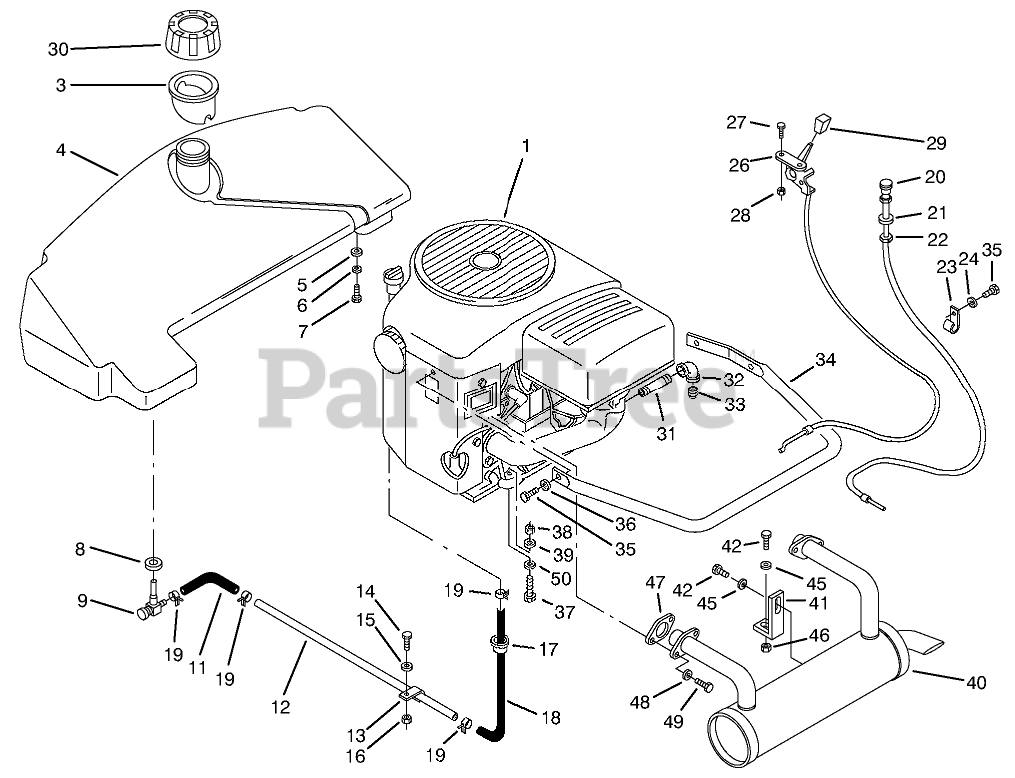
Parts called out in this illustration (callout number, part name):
1	Engine-16HP Model P216V-1/11103-D
3	FUNNEL-FUEL TANK
4	TANK-FUEL ASS'Y
5	WASHER-FLAT
6	WASHER-LOCK
7	SCREW-HH
8	BUSHING
9	VALVE-FUEL
11	HOSE-FUEL
12	TUBE FUEL LINE
13	J-CLIP
14	Bolt
15	WASHER-PLAIN
16	NUT-LOCK, NI
17	BUSHING-NYLON 1.093
18	Hose-18" Fuel
19	CLAMP-FUEL LINE
20	CONTROL-CHOKE
21	WASHER-FLAT
22	NUT-HEX PALNUT
23	CLIP
24	WASHER-FLAT
26	CONTROL-THROTTLE
27	SCREW-PPH
28	NUT-LOCK, NI
29	KNOB-CONTROL
30	GAS CAP ASM
31	NIPPLE-3/8 X 2.5
32	ELBOW 3/8 90 DEG
33	Plug
34	GUARD-AIR CLEANER
35	SCREW-HH
36	WASHER-LOCK
37	Bolt
38	NUT-LOCK, NI
39	WASHER-PLAIN
40	EXHAUST-MUFFLER
41	BRACKET-MUFFLER
42	SCREW-HH
43	WASHER-PLAIN
45	WASHER-PLAIN
46	NUT-LOCK, NI
47	GASKET
48	WASHER-LOCK
49	SCREW-HSH
50	WASHER
